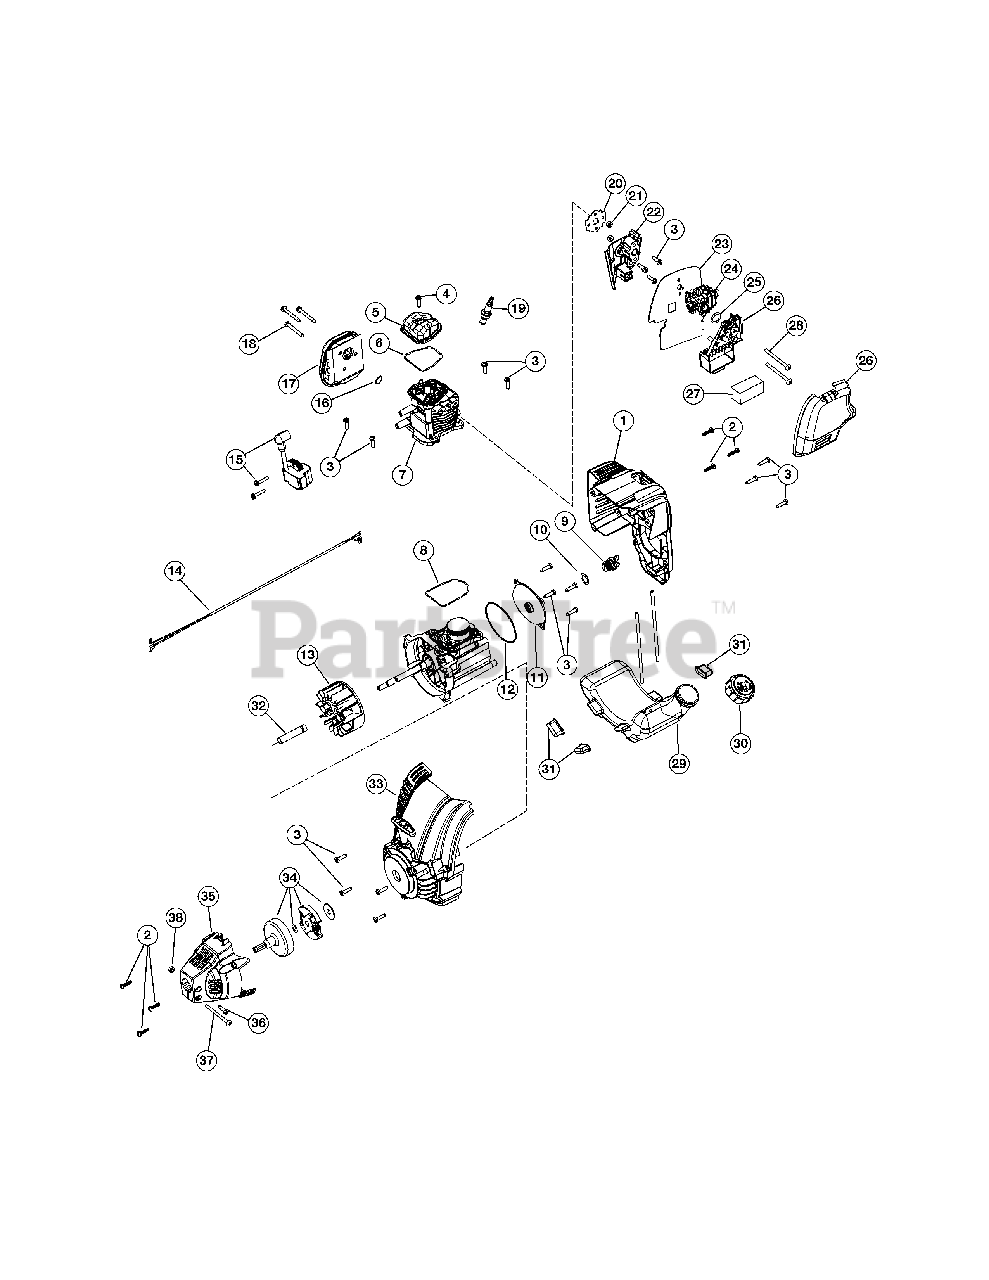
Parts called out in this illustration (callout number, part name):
1	Engine Cover Assembly (includes 2 & 3)
2	Cover Screw
3	Housing Screw
4	Rocker Cover Screw
5	Rocker Cover
6	Rocker Cover O-Ring
7	Cylinder Assembly (includes 3-6 & 8)
8	Cylinder O-Ring
9	Oil Plug (includes 10)
10	Oil Plug O-Ring
11	Crankcase Cover
12	Crankcase Cover O-ring
13	Flywheel Assembly
14	Lead Wires
15	Module Assembly
16	Muffler Gasket
17	Muffler Assembly (includes 16 & 18)
18	Muffler Screw
19	Spark Plug
20	Insulator Gasket
23	Carburetor Gasket
24	Carburetor
26	Air Cleaner Cover Assembly (includes 27)
27	Air Filter
29	Fuel Tank Assembly w/Fuel Lines (includes 30)
31	Fuel Tank Pads
33	Starter Housing Assembly (includes 3)
34	Clutch Drum Assembly
35	Clutch Cover (includes 2)
36	Anti-Rotation Screw
37	Clamp Screw
